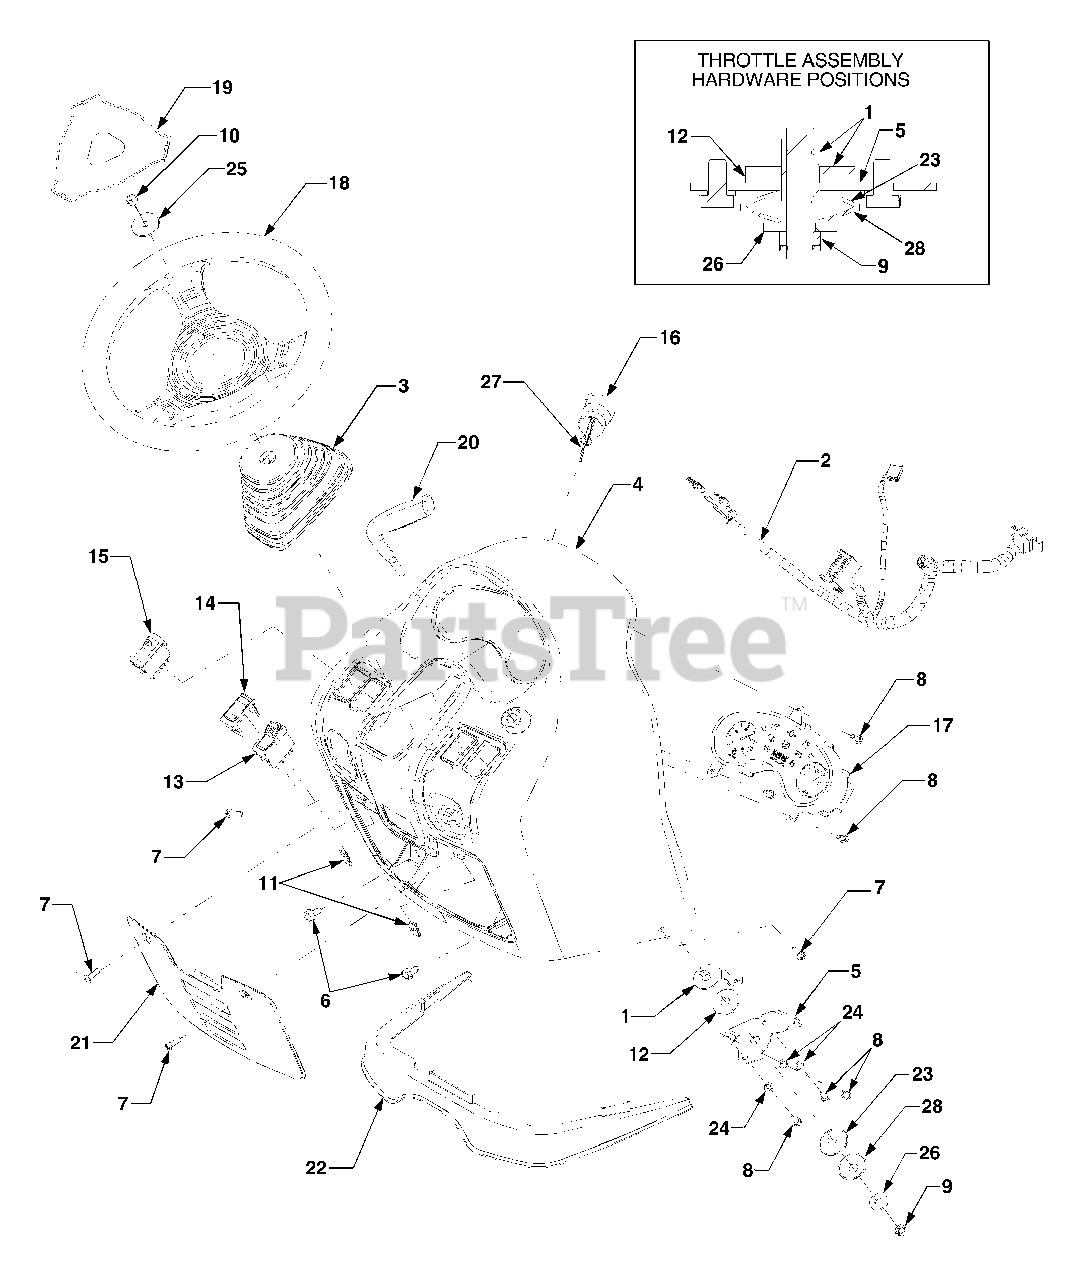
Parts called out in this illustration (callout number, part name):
3	Boot, Steering Shaft
4	Dash
5	Bracket, Throttle Mtg.
6	Screw, Hex Wash. Hd. Tapp 5/16-18 x .625
7	Screw, Pan Hd., 1/4-20 x .75
8	Screw, Hex Cap, 1/4-20 x .5 GR5
9	Nut, Hex Insert Jam Lock, 3/8-24
10	Nut, Hex Lock, 5/16-24
11	Nut, Speed, 1/4-20
12	Washer, Friction, .515 x 1.5 x .12
13	Switch, PTO
15	Switch, Headlight
16	Switch, Ignition
17	Panel, Instrument
18	Steering Wheel, Soft Grip
19	Cover, Steering Wheel
20	Handle, Throttle
21	Panel, Dash Insert
22	Extension, Dash
23	Washer, Belleville, .531 x 1.62 x .045
24	Washer, Lock, 1/4
25	Washer, Flat, .344 x 1.5 x .1
26	Washer, Flat, .406 x 1.0 x .105
27	Key Set, Ignition
28	Washer, Spher., .39 x 1.62 x .045
